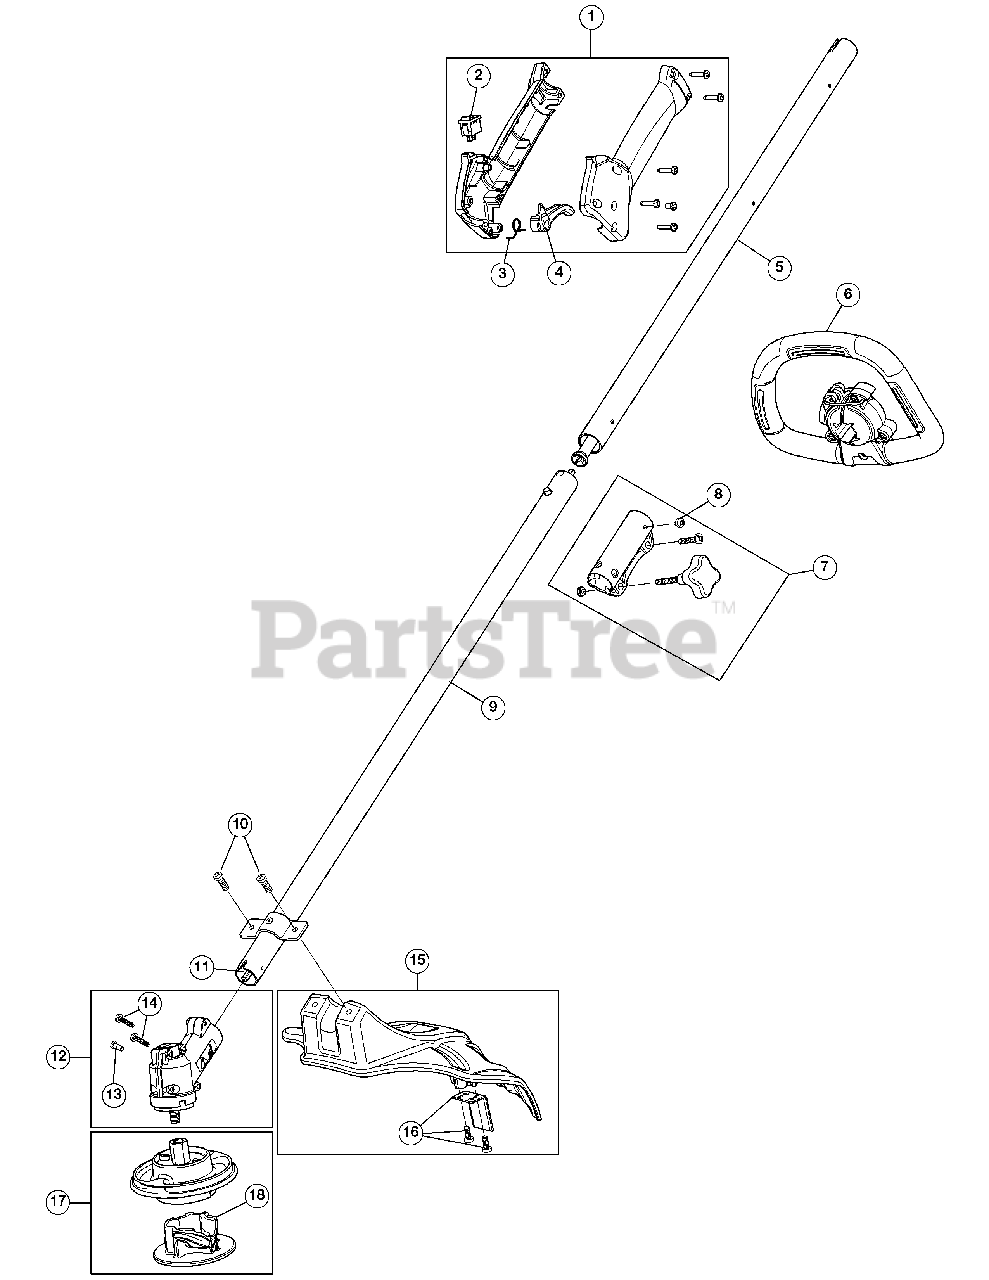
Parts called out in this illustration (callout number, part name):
1	Throttle Housing Assembly (Incl. 2 - 4)
2	Trigger Switch Assembly
3	Throttle Trigger Spring
4	Throttle Trigger
5	Upper Drive Shaft Assembly
6	Handle
7	Split Boom Coupler (Incl. 8)
8	Coupler Anti-Rotation Screw
9	Lower Drive Shaft Housing
10	Shield Mounting Screws
11	Lower Flexible Drive Shaft
12	Gearbox Assembly (Incl. 13 and 14)
13	Gearbox Anti-Rotation Screw
14	Gearbox Screw
15	Shield Assembly (Incl. 16)
16	Blade Assembly
17	Cutting Head Assembly (Incl. 18)
18	Cutting Head Cap
